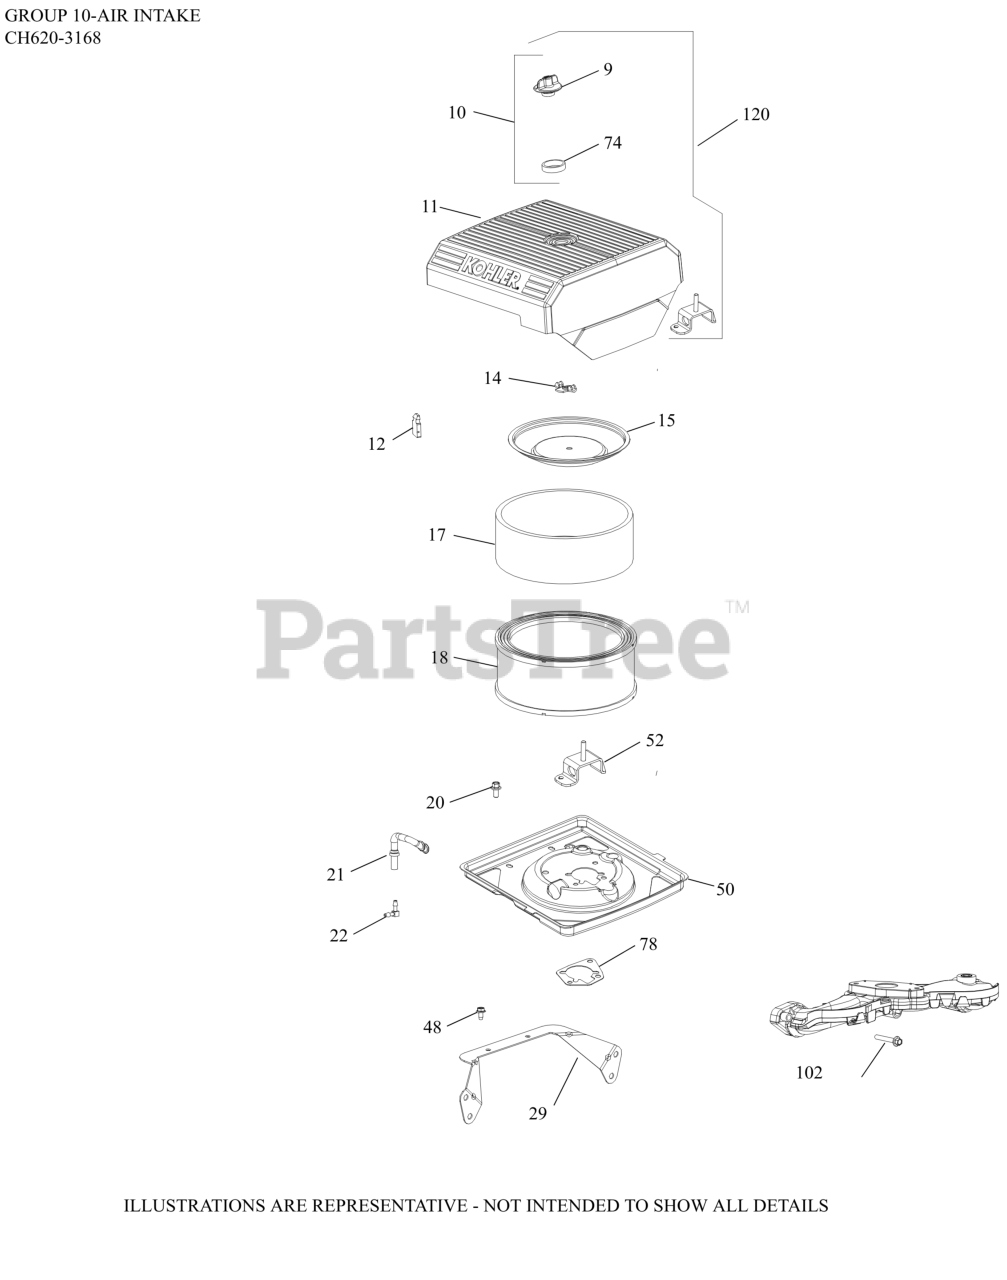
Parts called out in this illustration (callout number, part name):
9	KNOB, COVER
10	KIT, KNOB W/SEAL
11	COVER, AIR CLEANER
12	SEAL, INNER AIR CLEANER
14	NUT, WING
15	COVER, INNER AIR CLEANER
17	PRE CLEANER LOW ELEMENT
18	ELEMENT, AIR CLEANER
20	SCREW, FLG THD FRM M6X1.0X16
21	HOSE, EVAP
22	CONNECTOR, EVAPORATIVE HOSE
29	AIR CLEANER BRACKET
48	SCREW, THREAD FORMING
50	KIT, AIR CLEANER BASE
52	BRACKET, AIR CLEANER
78	GASKET, AIR CLEANER BASE
102	SCREW, FLG M6X1.0X40
120	KIT, AIR CLEANER COVER
